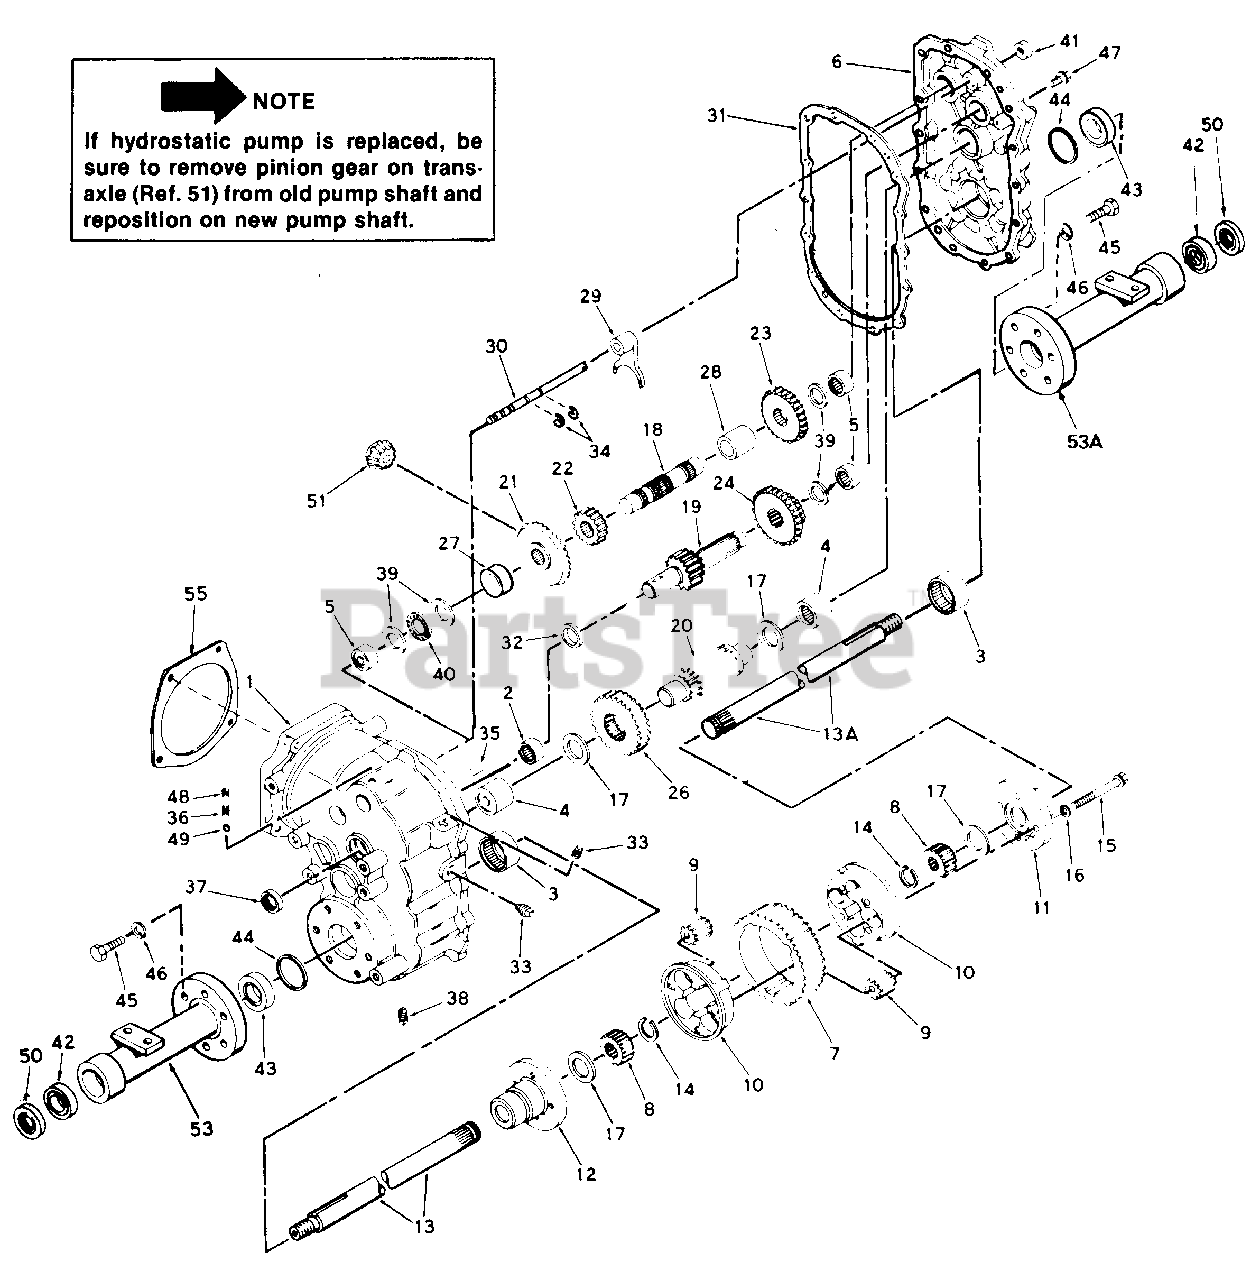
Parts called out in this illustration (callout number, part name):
1	Case Ass'y., Transaxle
2	Bearing, Needle
3	Bearing, Needle
4	Bearing, Needle
5	Bearing, Needle
6	Cover Ass'y., Transaxle
7	Gear, Ring
8	Gear, Side
9	Gear, Pinion
10	Core, Body
11	Carrier. Differential
12	Carrier, Differential
13	Axle, 18 17/64" Long
13A	Axle, 15 29/64" Long
14	Ring, Snap
15	Screw, Hex Hd. Mach., 3/8-16 x 3-3/8
16	Lock Washer, 3/8"
17	Washer, Thrust
18	Shaft, Counter
19	Shaft, Brake
20	Pinion, Output
21	Gear, Bevel (30 Teeth)
22	Gear, Spur (16 Teeth)
23	Gear, Spur (23 Teeth)
24	Gear, Cluster (20 and 27 Teeth)
26	Gear, Output (37 Teeth)
27	Spacer (55/64" Long)
28	Spacer (1 19/32" Long)
29	Fork, Shift
30	Rod, Shift
31	Gasket, Case and Cover
32	Spacer
33	Plug, Pipe
34	Ring, Snap
35	Pin, Dowel
36	Spring
37	Seal, Oil
38	Plug, Magnetic Drain
39	Washer, Thrust
40	Bearing, Thrust
41	Seal, Oil
42	Bearing, Ball
43	Bearing, Thrust
44	Seal, Square Cut
45	Screw, Hex Hd. Mach., 1/2-13 x 1 1/2
46	Lock Washer, 1/2"
47	Screw, Hex Hd. Thd. Forming, 5/16-18 x 1
48	Screw, Set 1/4-20 x 1/2
49	Ball, Steel
50	Seal, Oil
51	Pinion, Bevel
53	Housing, Axle (9-1/4" Long)
53A	Housing, Axle (7-5/16" Long)
55	Gasket
